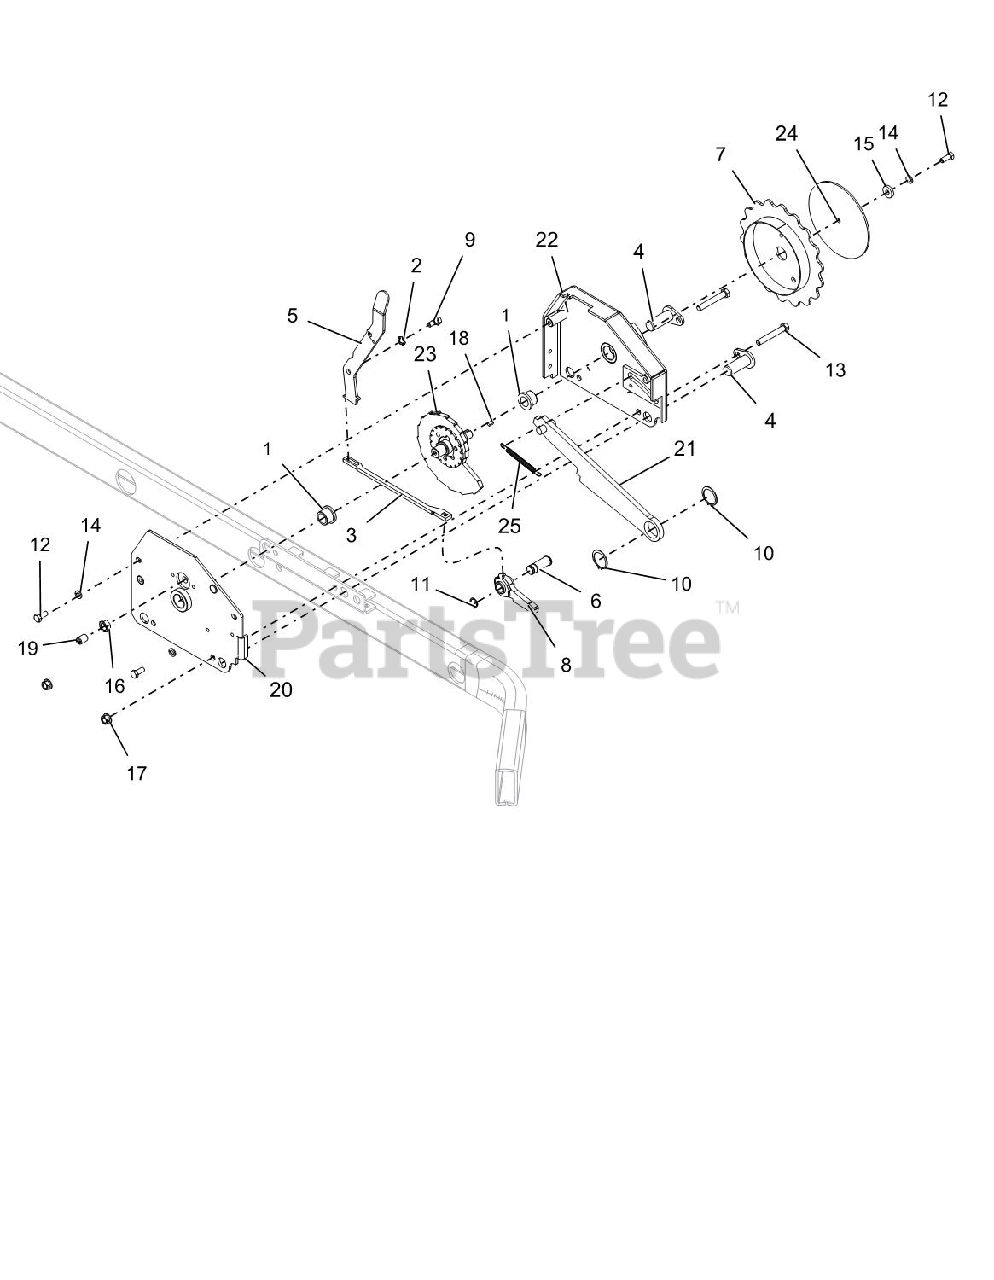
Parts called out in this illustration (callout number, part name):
1	BUSHING, FLANGE .75X.75X1.0
2	WAVE WASHER .390X.655X.110
3	LINK, TRANSPORT LOCK
4	WLDMT, PIN HOC MOUNTING
5	LEVER, TRANSPORT LOCK
6	PIN, CLEVIS .625 SNAP RING
7	WLDMT, DIAL HOC
8	WLDMT, LOCK PAWL
9	BOLT, SHLDR .31-18 X .25
10	RG-RET-EXT 1.25 X .050
11	RG-RTNG-EXT .625X.050
12	BLT-HEX .31-18X.75 GR5 YWZC
13	BLT-HEX .38-16X2.50 GR5 YWZC
14	WSHR-LK .31X.078 REG YWZC
15	WSHR-FL-STL .328X.87X.179 YWZC
16	NUT-JAM .50-13 YWZC
17	NUT-LK-CTR-FLG .38-16 YWZC
18	KEY-SQ .188X.188X.375
19	BALL SPRING PLUNGER, .500-13
20	WLDMT, HOC OUTER
21	HOC LINK WLDMT - BLK
22	HOC INNER WLDMT - RED
23	WLDMT, CAM, HOC
24	DIAL PLATE - RED
25	SPRING, EXT
